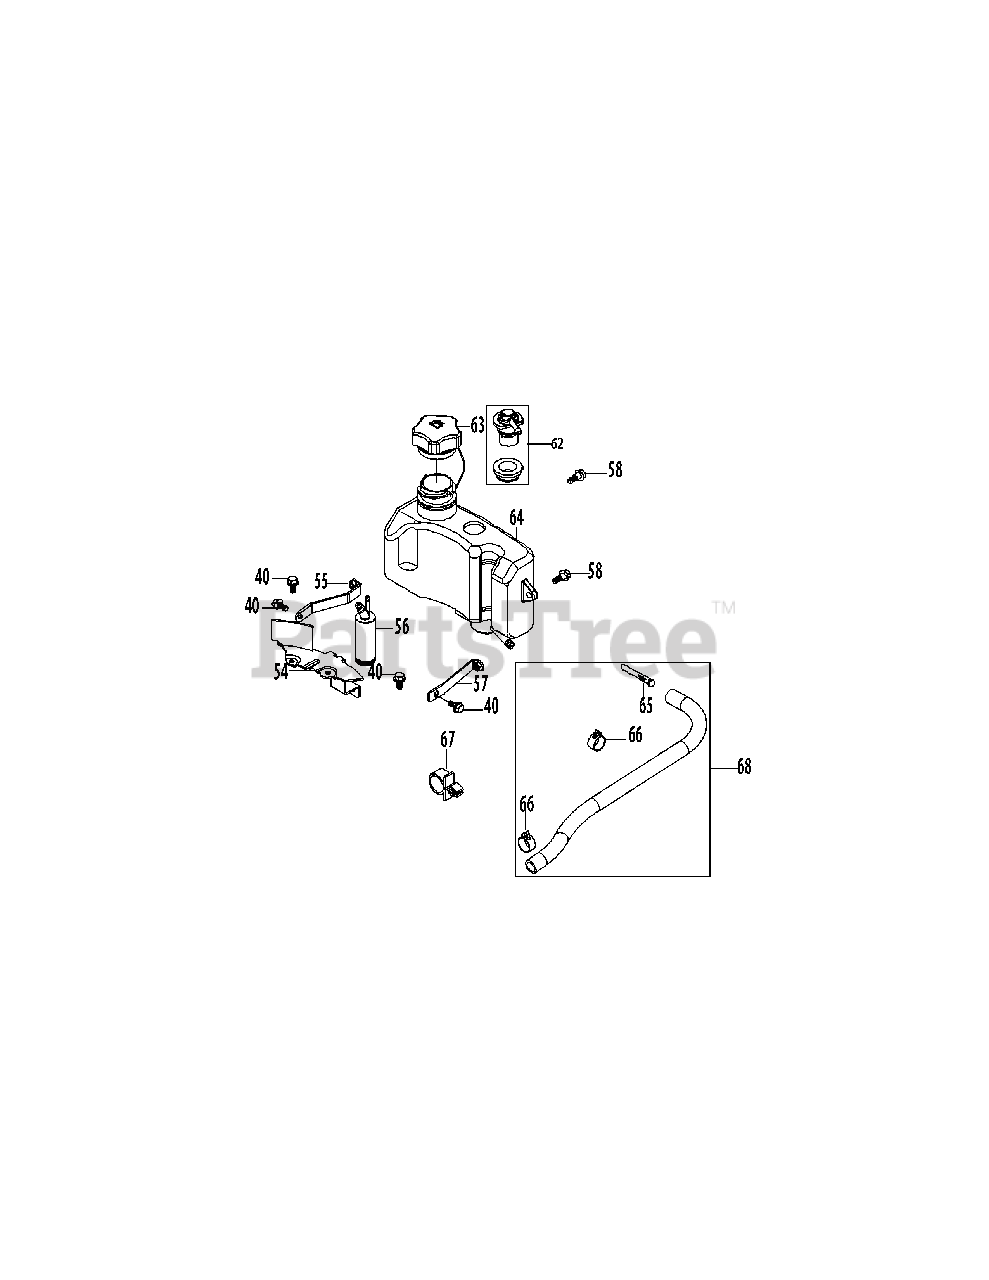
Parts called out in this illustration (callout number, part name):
40	Bolt M6×14
54	Fuel Tank Bottom Bracket
55	Righthand Tank Bracket
56	Carbon Canister
57	Leftthand Tank Bracket
62	Roll Over Valve Assembly
63	Fuel Cap
64	Fuel Tank
65	Fuel Filter
66	Fuel Hose Clamp
67	Plastic Support Clamp
68	Fuel Line Kit
